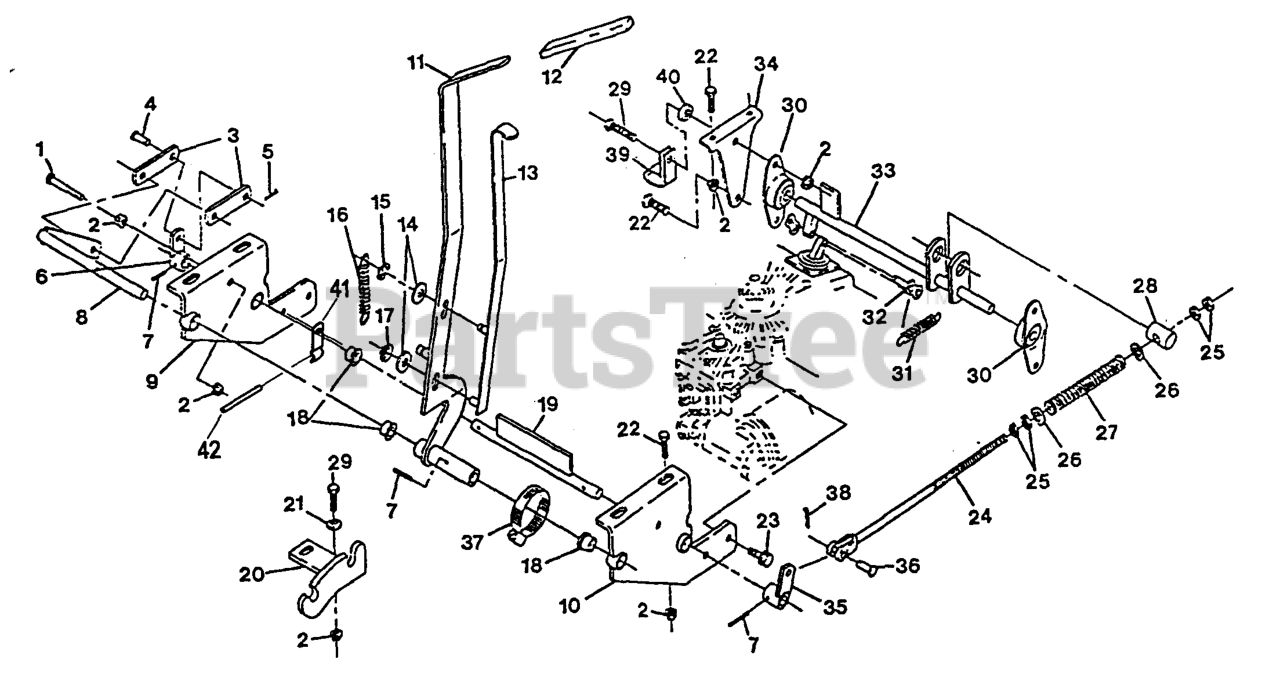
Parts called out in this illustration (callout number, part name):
3	LINK,BRAKE PLTD
4	PIN-CLEVIS
6	WLD,CONTROL ARM
8	PIVOT - BRKT/LEVER
10	WLD,TRANSAXLE SUPPORT RH
12	GRIP-LEVER
16	SPRING,BRAKE HANDLE
17	NUT,PUSH
18	BEARING-CONTROL
19	WLD,BUTTERFLY
20	WLD,BRAKE QUADRANT
21	WASHER-SPRING
24	LINKAGE,BRAKE
27	SPRING,COMPRESSION
28	PIN,TRUNION
30	FLANGE MTG, SIDE
32	LINK,CONNECTING
33	Jackshaft, Brake
35	WLD,BRAKE CONTROL ARM
36	PIN-CLEVIS
37	CLAMP-HOSE
40	SPACER,CLUTCH ANCHOR
41	SPRING,DUMP VALVE
42	ROLLPIN PLTD
